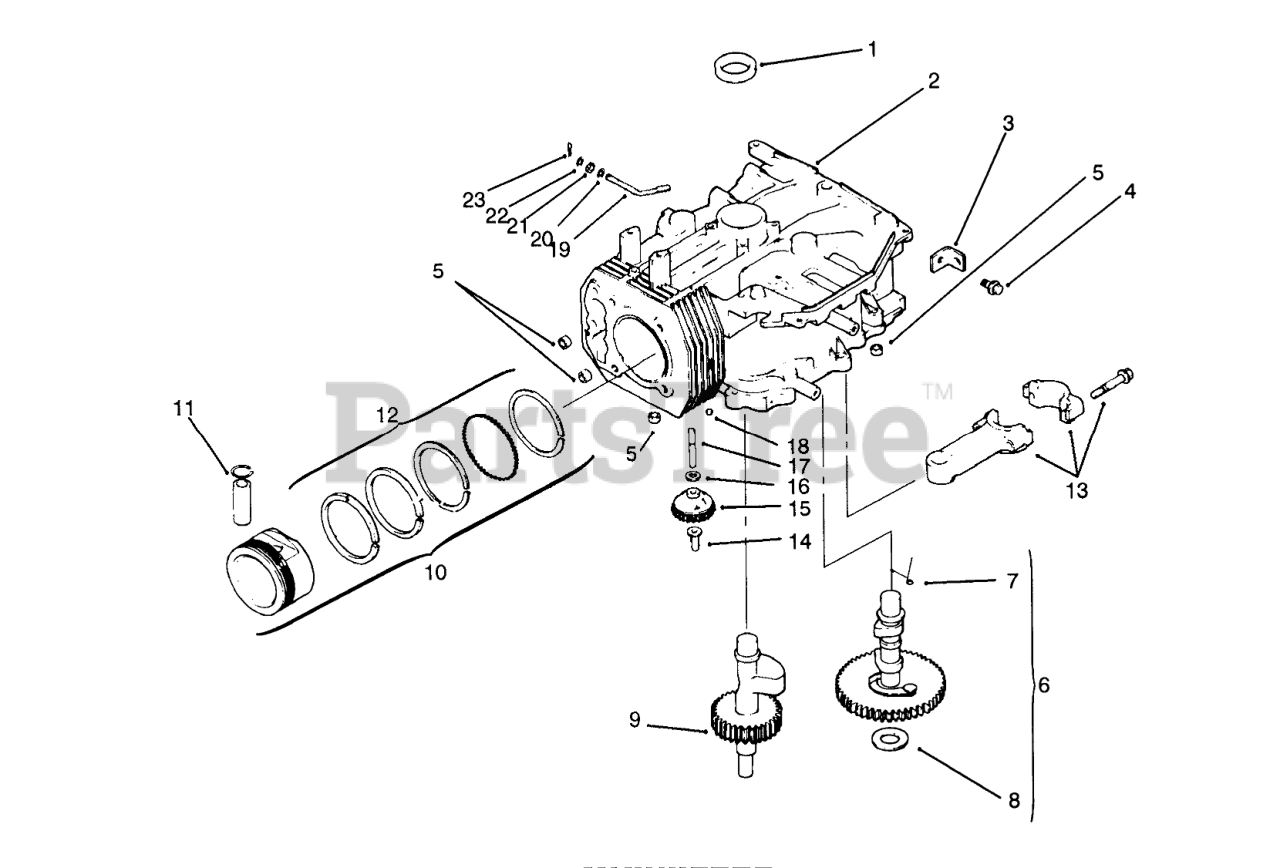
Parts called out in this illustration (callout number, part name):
1	Seal-Crankshaft (Only On: 72042,72043,72062,72063)
3	Strap-Lifting (Only On: 72042,72043,72062,72063)
4	Screw M8x1.25x22 (Only On: 72042,72043,72062,72063)
5	Dowel-Locating (Only On: 72042,72043,72062,72063)
6	Kit-Camshaft INCL 7-8 (Only On: 72042,72043,72062,72063)
7	Spring-Actuating (Only On: 72042,72043,72062,72063)
8	Shim-Camshaft A/R (Only On: 72042,72043,72062,72063)
9	Shaft-Balance (Only On: 72042, 72043, 72062, 72063)
10	Piston ASM STD INCL 11-12 (Only On: 72042,72043,72062, 72063)
10	Piston ASM .25 INCL 11-12 (Only On: 72042,72043,72062, 72063)
10	Piston ASM .50 INCL 11-12 (Only On: 72042,72043,72062, 72063)
11	Retainer-Piston Pin (Only On: 72042, 72043,72062,72063)
12	Ring Set STD (Only On: 72042,72043,72062,72063)
12	Ring Set .25 (Only On: 72042,72043,72062,72063)
12	Ring Set .50 (Only On: 72042,72043,72062,72063)
13	Connecting Rod STD (Only On: 72042,72043,72062,72063)
13	Connecting Rod .25 (Only On: 72042,72043,72062,72063)
14	Pin-Governor Regulating (Only On: 72042,72043,72062,72063)
15	Gear-Governor ASM (Only On: 72042,72043,72062,72063)
16	Washer-Governor (Only On: 72042,72043,72062,72063)
17	Shaft-Governor Gear (Only On: 72042,72043,72062,72063)
18	Plug-Cup (Only On: 72042,72043,72062,72063)
19	Shaft-Governor Cross (Only On: 72042,72043,72062,72063)
20	Washer-Governor Shaft (Only On: 72042,72043,72062,72063)
21	Seal-Governor Shaft (Only On: 72042,72043,72062,72063)
22	Washer-Flat (Only On: 72042,72043,72062,72063)
23	Pin-Governor Hitch (Only On: 72042,72043,72062,72063)
